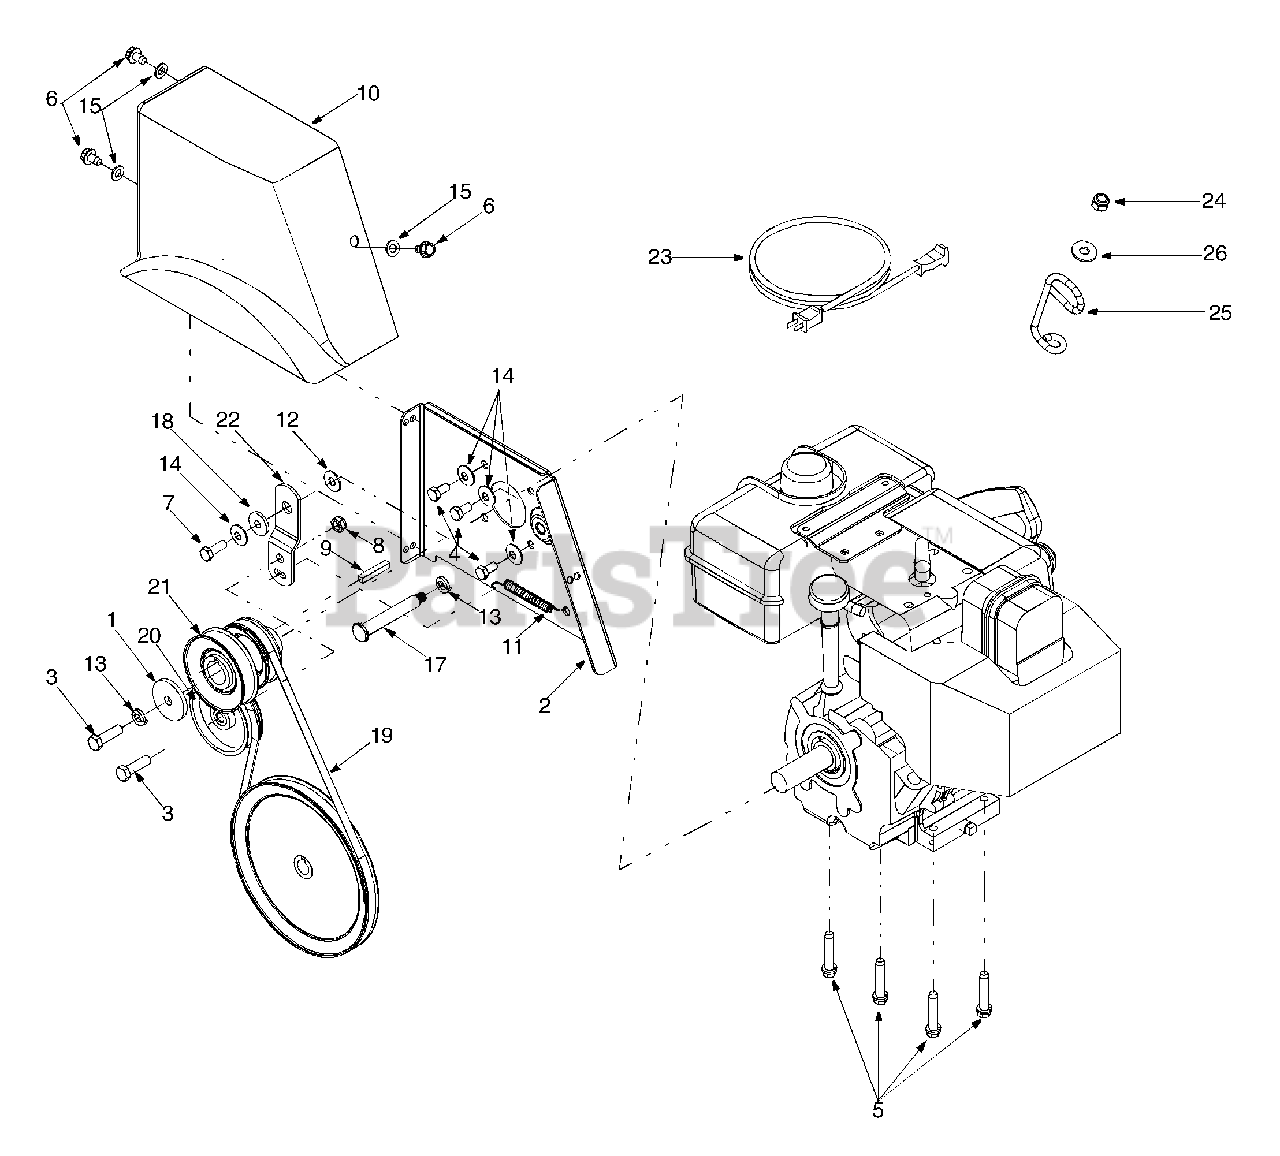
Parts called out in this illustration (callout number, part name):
4	Hex Screw 5/16-24 x .625"
5	Self-tapping Sems Screw
6	TT Screw 5/16-18 x 0.5"
7	Hex Lock Screw 5/16-24 x 1.25"
10	Belt Cover
11	Extension Spring
12	5/16 Washer
13	Lock Washer
14	Belleville Washer
15	Flat Washer
17	Shoulder Screw
18	Shoulder Spacer
19	V-Belt
20	Flat Idler
21	Double Pulley
22	Idler Bracket
23	Extension Cord, 110V, 3-prong
24	Hex Lock Nut 1/4-20
25	Cable Control Wire
26	Flat Washer
